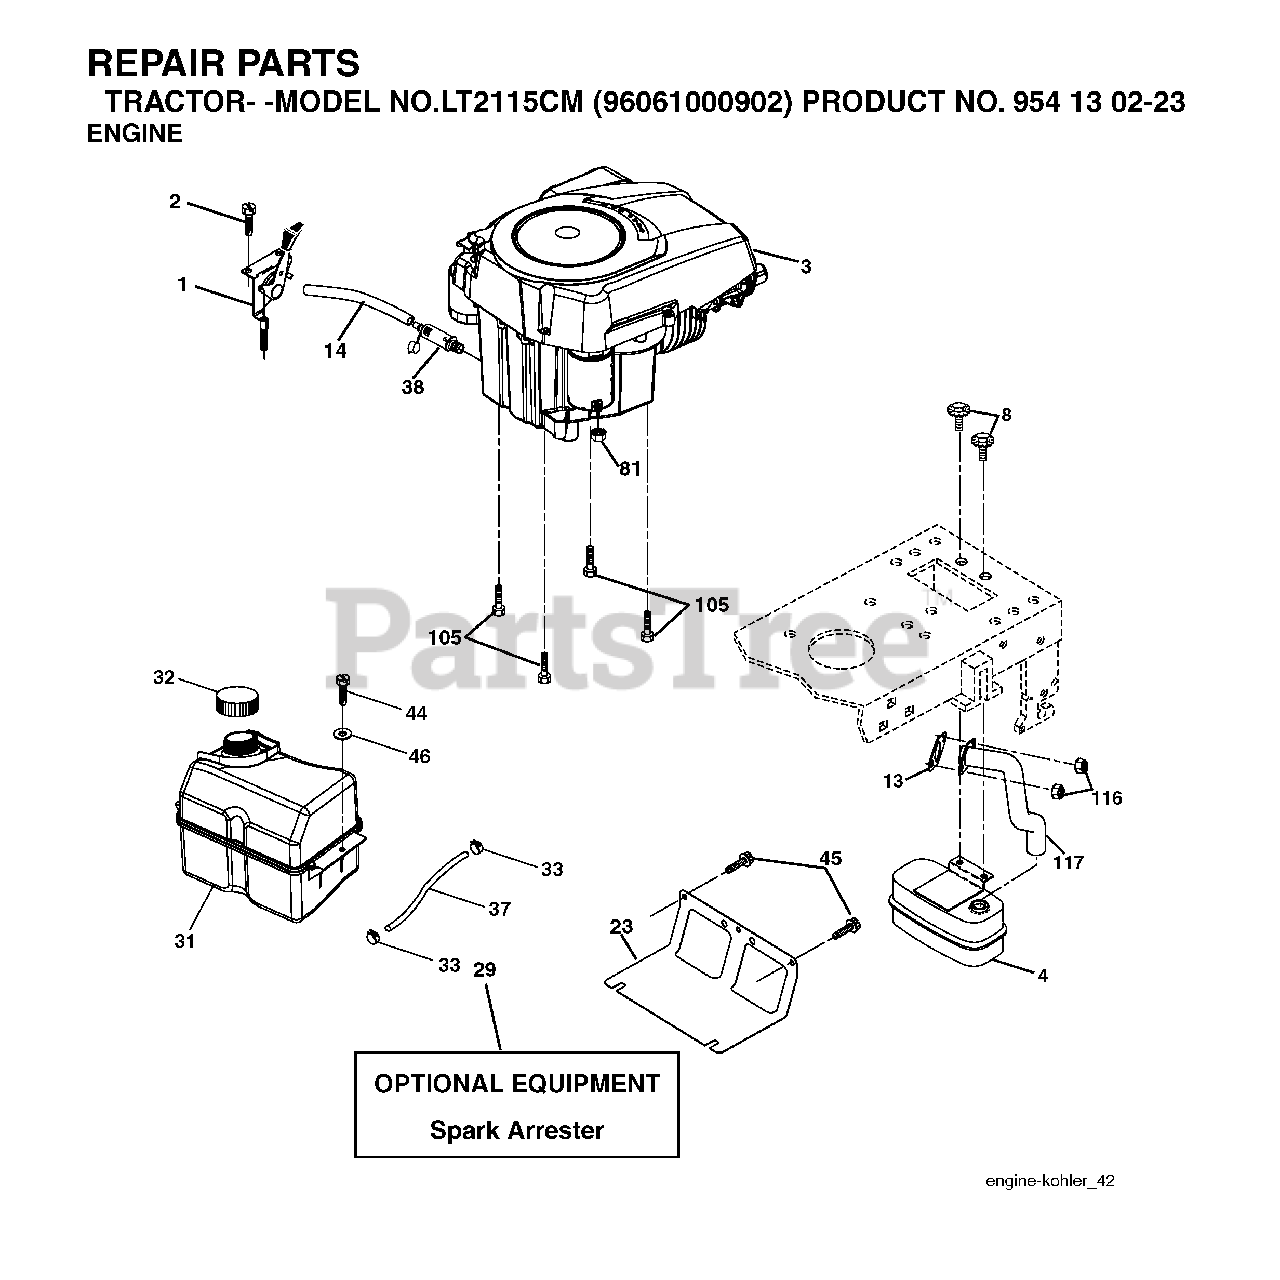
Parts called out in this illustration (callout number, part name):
1	CONTROL.THROTTLE.LT/YT
2	SCREW
4	MUFFLER.SINGLE.CYL.KOHL/B&S
8	BOLT, 5/16-18 X 1 3/4
13	GASKET ENGINE
14	TUBE, DRAIN OIL ASM.
23	SHEILD.BROWNING.DBR.GUARD
29	ARRESTER SPARK (OPTIONAL)
31	TANK FUEL
32	FUEL CAP
33	HOSE CLAMP
37	LINE.FUEL.20
38	PLUG DRAIN OIL EASY
44	SCREW HEXWSHR 1/4-20X3/4
45	SCREW, 3/8-16X3/4
81	NUT
105	SCREW 3/8-16X1
116	NUT.HEX.FLANGE.TOPLOCK
117	TUBE EXHAUST
